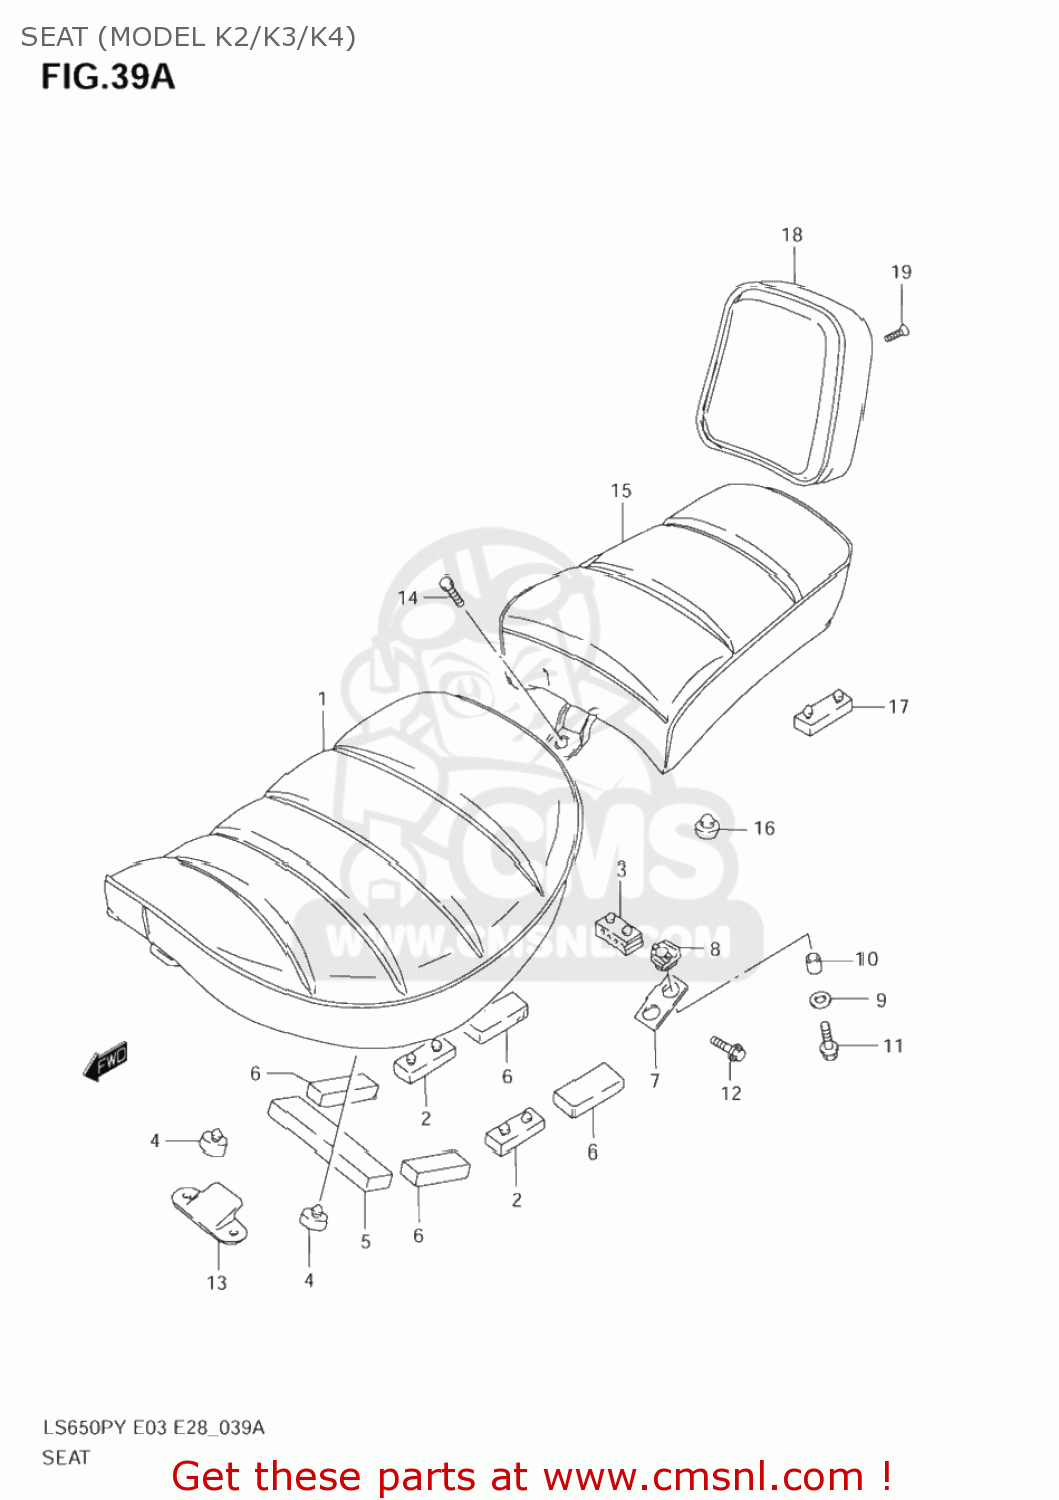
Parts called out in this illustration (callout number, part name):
1	SEAT SET
2	CUSHION,SEAT
3	CUSHION,SEAT(40X20X15)
4	CUSHION(11.5X22X20)
5	CUSHION,CTR FR
6	CUSHION,CTR SIDE
7	BRACKET,SEAT RR
8	CUSHION,SEAT RR BRACKET
9	WASHER(6.5X20X1.6)
10	COLLAR,SEAT(TS-5A1-02273)
11	BOLT
12	BOLT
13	PLATE,SEAT HOOK FR
14	BOLT
15	SEAT SET,PILLI
16	CUSHION,SEAT
17	CUSHION,SEAT
18	PAD ASSY,SEAT
19	SCREW,SUNVISOR
